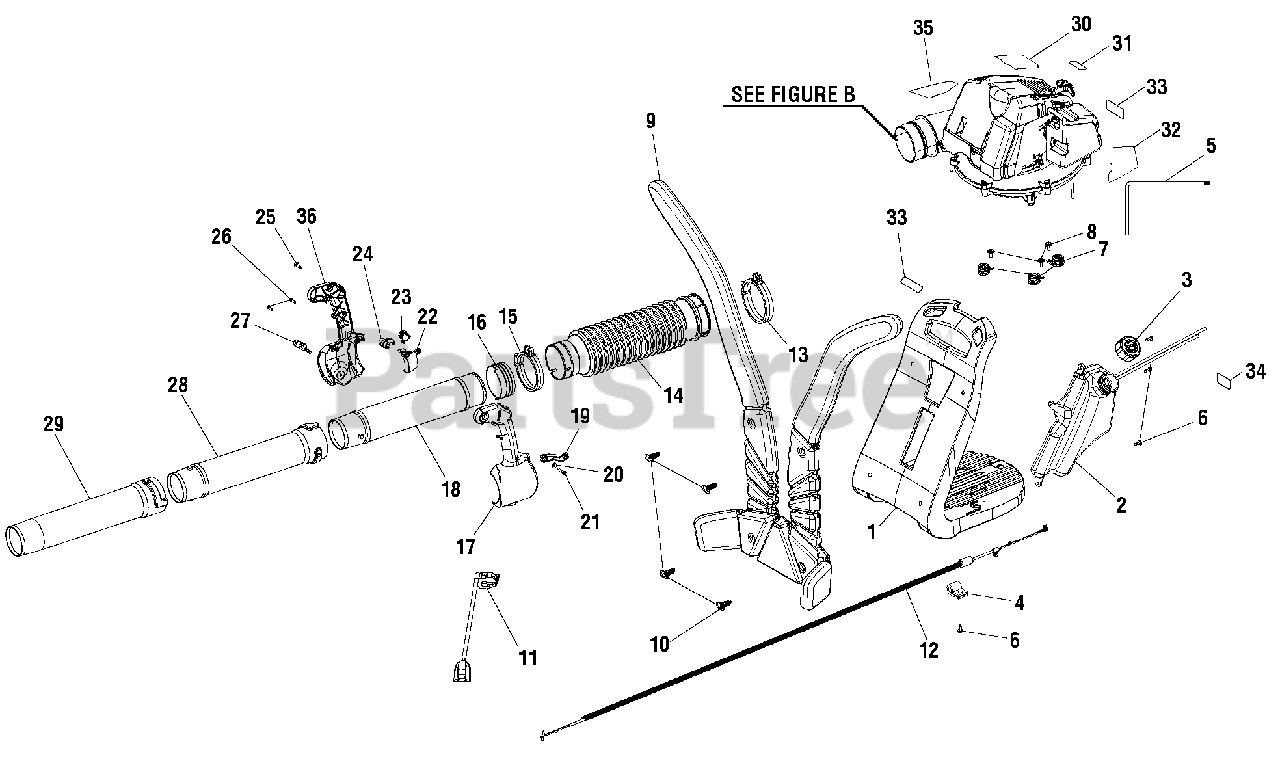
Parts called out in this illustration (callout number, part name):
2	Fuel Tank Assembly
3	Fuel Cap Assembly
4	Cable Clamp
5	Wrench (L-25)
6	Screw (10-14 x 14 mm)
8	Screw (10-14 x 16 mm)
10	Harness Snap Fastener
11	Ignition Module Assembly
12	Throttle Cable
13	Clamp Assembly (Large)
15	Clamp Assembly (Small)
16	Upper Blower Tube Bushing
17	Left Hand Handle
18	Upper Tube
19	Cruise Lever
20	Washer (OD12 x ID4.3 x 1.5t)
21	Screw (8-14 x 25 mm)
23	Stop Switch
24	Trigger Lock
25	Screw (10-14 x 3/4 in.)
26	Screw (M4 x 16 mm, Pan Hd.)
28	Intermediate Tube
29	Tube Nozzle
30	Model Label
31	Choke Label
32	Start Instructions Label
33	Logo Label
34	Warning Label
35	Combustion Warning Label
36	Right Hand Handle
